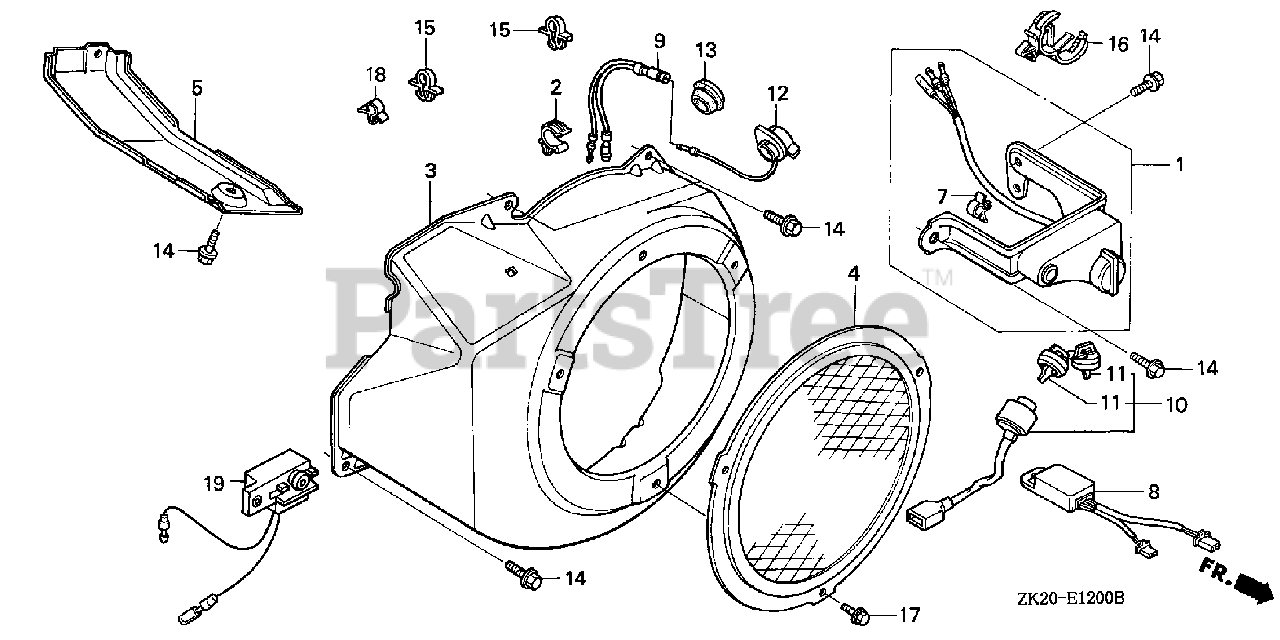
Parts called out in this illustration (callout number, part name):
2	CLIP, TUBE
3	COVER, FAN *R8* (BRIGHT RED)
3	COVER, FAN *NH1* (BLACK)
5	SHROUD
12	SWITCH ASSY., ENGINE STOP
14	BOLT, FLANGE (6X12) (CT200)
16	CLIP, WIRE HARNESS
